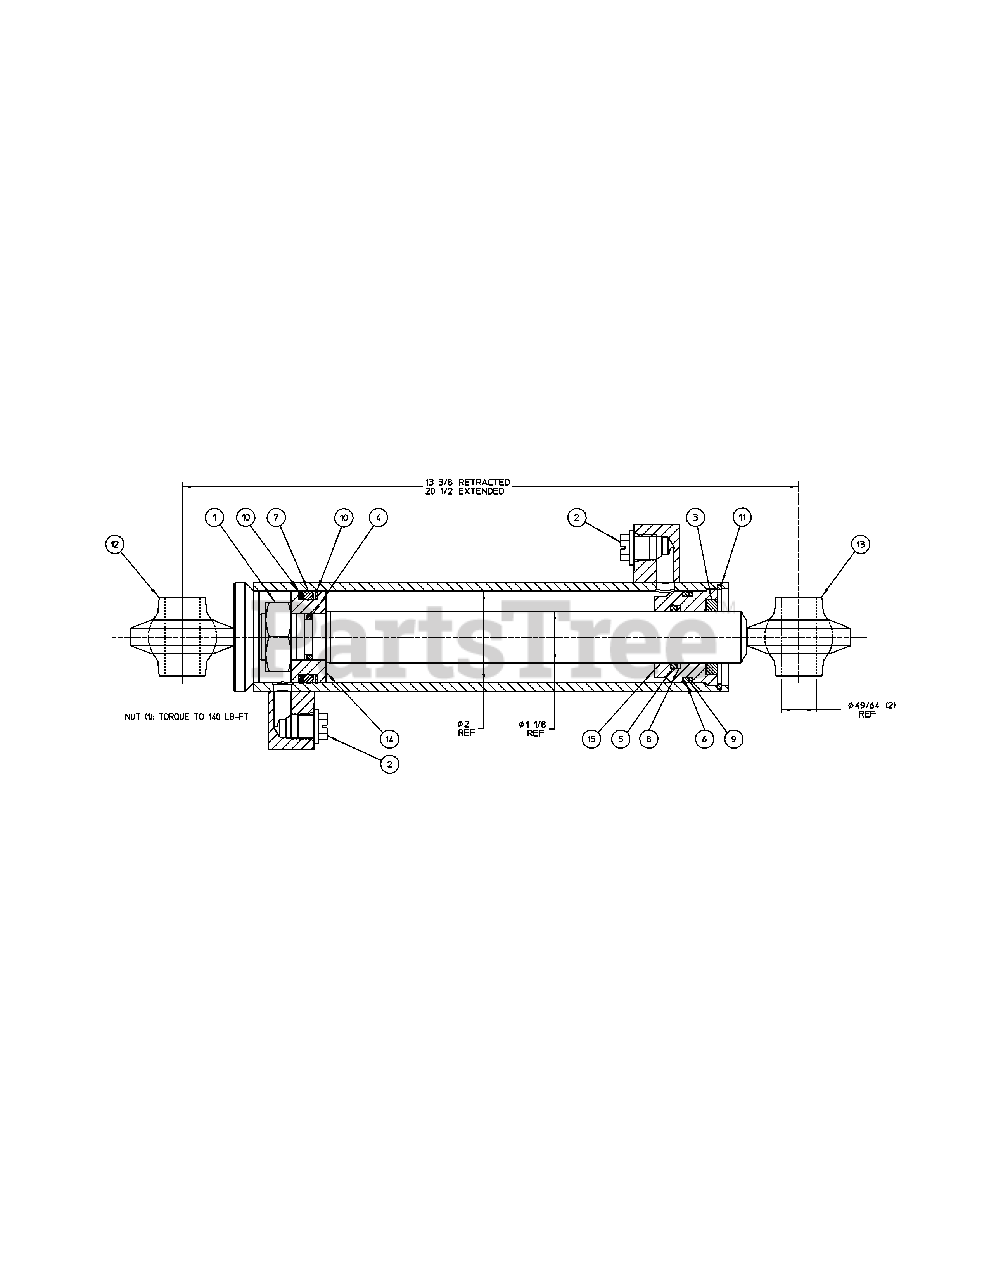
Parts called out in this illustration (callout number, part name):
1	Nut, Hex 1-14 Lock
2	Cap Plug, 9/16-18 Thread with O-Ring
3	Oil Seal
4	O-Ring, 1" OD x 3/4 ID
5	O-Ring, 1-3/8 OD x 1-1/8 ID
6	O-Ring, 2" OD x 1-3/4 ID
7	O-Ring, 2" OD x 1-5/8 ID
8	Leather Washer
9	Back Up Ring
10	Back Up Ring
11	Retaining Ring
12	Cylinder Tube Weldment
13	Piston Rod Weldment
